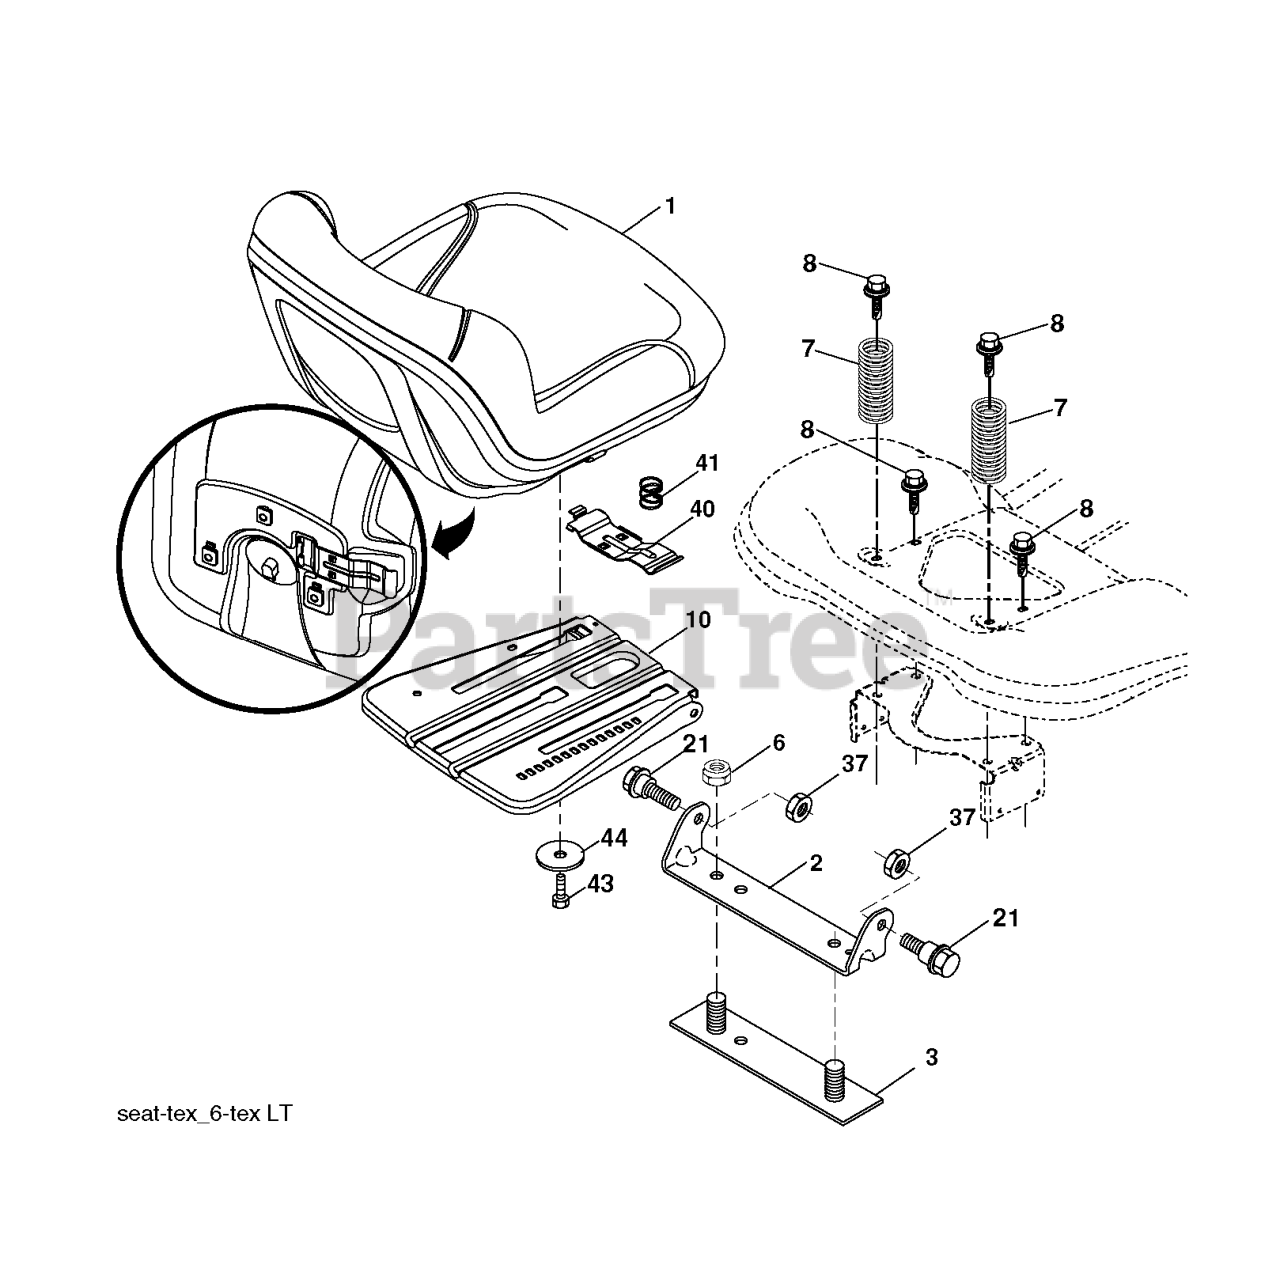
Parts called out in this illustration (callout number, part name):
1	RP SEAT.TH130.GRY.MILSCO.
2	BRKT.PIVOT.FENDER
3	STRAP
6	NUT
7	SPRING COMPRESSION
8	BOLT.5/16-18UNCX3/4 W/SEMS.BLK
10	PAN.ASM.SEAT.3PT
21	BOLT.SHOULDER.5/16-18
37	NUT.71038.31-18.HEX.NYLOCK
40	HANDLE.SLIDE.SEAT.TEX.BLACK
41	SPRING.LATCH.SEAT.TEX
44	WASHER 13/32 X 2-3/8 X 12GA
